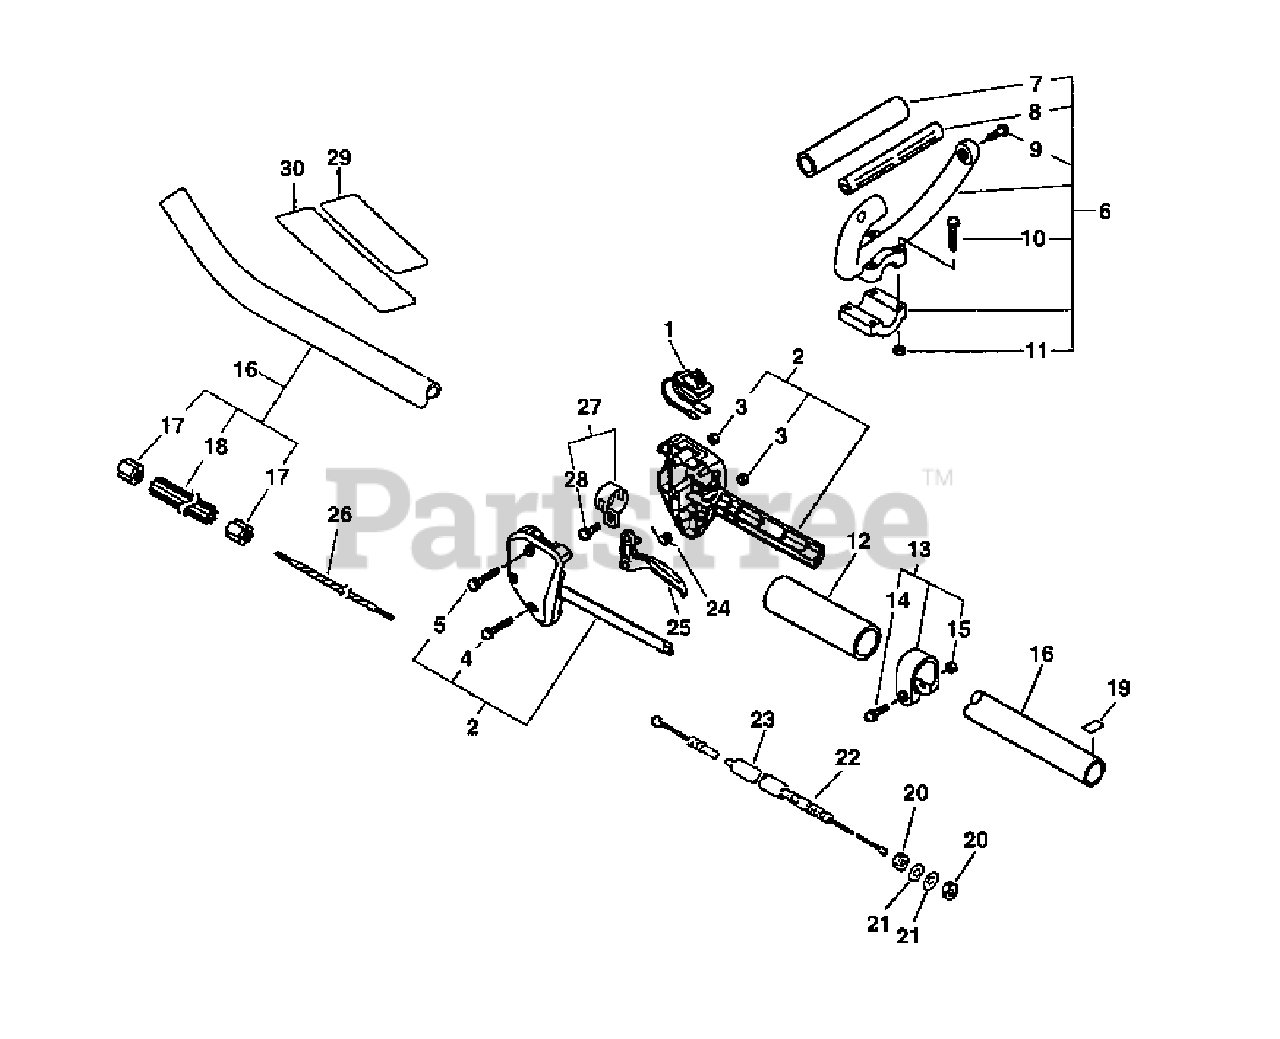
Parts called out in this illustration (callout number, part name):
1	IGNITION SWITCH ASSY
2	HANDLE KIT, CONTROL
3	NUT M5
4	SCREW 5×25
5	SCREW 5×35
6	LOOP HANDLE ASSY
7	GRIP, HANDLE
9	SCREW 5×30
10	SCREW 6×25
11	NUT, HEX M6
12	GRIP, HANDLE
13	CLAMP KIT
14	SCREW 5×28
15	NUT M5
16	MAIN PIPE ASSY
18	LINER, FLEXIBLE 21.6×1420
19	LABEL - ALIGNMENT
21	WASHER 6.5×11.5×0.8
22	CABLE, THROTTLE
23	TUBE
24	SPRING, TORSION
25	TRIGGER, THROTTLE
26	DRIVESHAFT - FLEXIBLE L= 1522
27	CLAMP KIT
28	SCREW 5×14
29	LABEL, CAUTION
29	LABEL - CAUTION
30	LABEL, CAUTION
